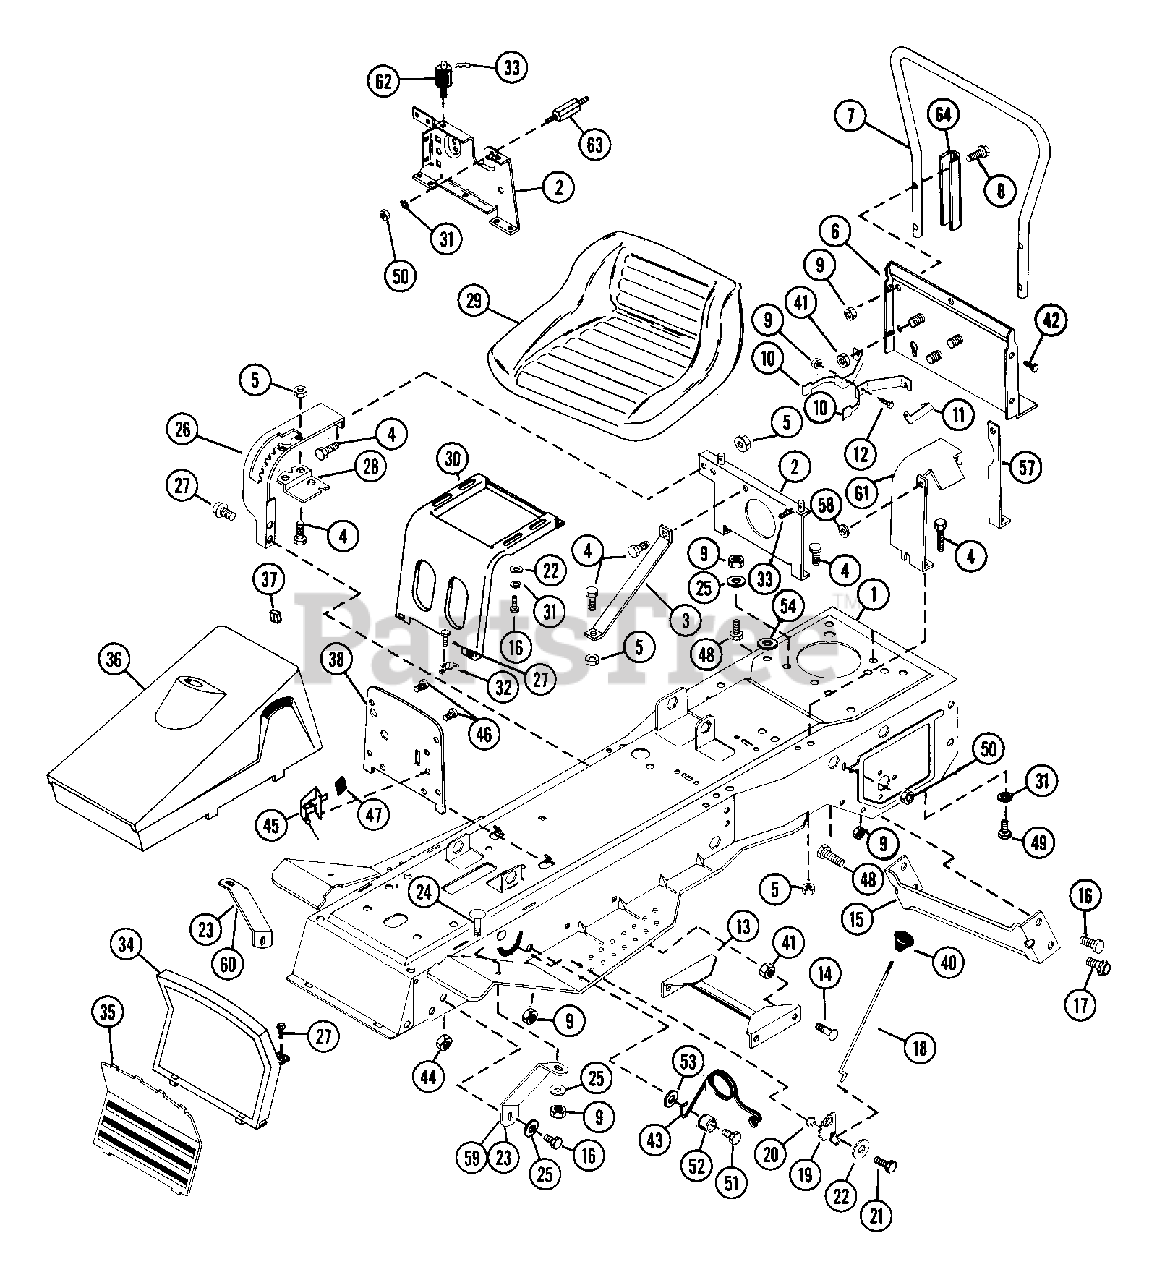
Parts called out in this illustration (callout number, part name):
1	FRAME
2	SEAT LEG
3	BRACE
4	BLT-HEX .25-20X.50 PL GR2
5	NUT-LK-CTR .250-20 PL
6	BACK COVER
7	TUBE
8	BLT-HEX .31-18X1.50 PL GR2
9	NUT-LK .312-18 GR A PL
10	BELT FINGER
11	BELT FINGER BRACE
12	BLT-HEX .31-18X.75 PL GR2
13	FRAME BRACE
14	BLT-RDHDSQNK .312-18X.62SHTPL
15	FRAME BRACE
16	BLT-HEX .31-18X.63 PL GR 2
17	SCR-TAP .312-18X1.50 HWH PL TR
18	PARKING BRAKE ROD
19	BRAKE LATCH
20	SPACER -SHLD .344X.500X.469
21	BLT-HEX .31-18X1.00 PL GR 2
22	WSHR-FL-STL .38X.875X.083 PL
23	FENDER BRACE
24	BLT-RDHDSQNK .31-18X.75 SHT PL
25	WSHR-FL-STL .323X.625X.062 PL
26	QUADRANT
27	BLT-SERHFWH .25-20X.50 PL
28	BRACKET NEUTRAL SWITCH
29	SEAT
30	SEAT BRACKET
31	WSHR-LK .312X.097 PL HVY
33	PIN-HAIR INT .08X.18X1.18
34	GRILLE INSERT
35	GRILLE
37	PLASTIC GROMMET
38	DASH PANEL
39	SCR-TAP 10-24X.375 CRPH 1A
41	NUT-FLG. .312-18 PL
42	BLT-SERHFWH .31-18X.50 PL
43	SG-TORS .125X1.0X1.75
44	NUT-LK-TWIN .312-18 PL
45	THROTTLE CONTROL
46	SCR-TAP 10-12X.50 CRPH PL A BL
48	BLT-HEX .31-18X1.25 PL GR2
49	BLT-HEX .31-18X.75 PL GR5
50	NUT-HEX .312-18
51	BLT-HEX .31-18X.63 PL GR 2
52	SPACER
53	WSHR-FL-STL .344X1.125X.063PL
54	LABEL,CONT. PAN. (FR 128854)
56	NUT-LK-CTR .250-20 PL
57	BRACE
58	GROMMET, .31 ID
59	L H FENDER BRACE
60	RH FENDER BRACE
61	SHIELD
62	ISOLATION MOUNT
63	STUD SPACER
64	BRACE
